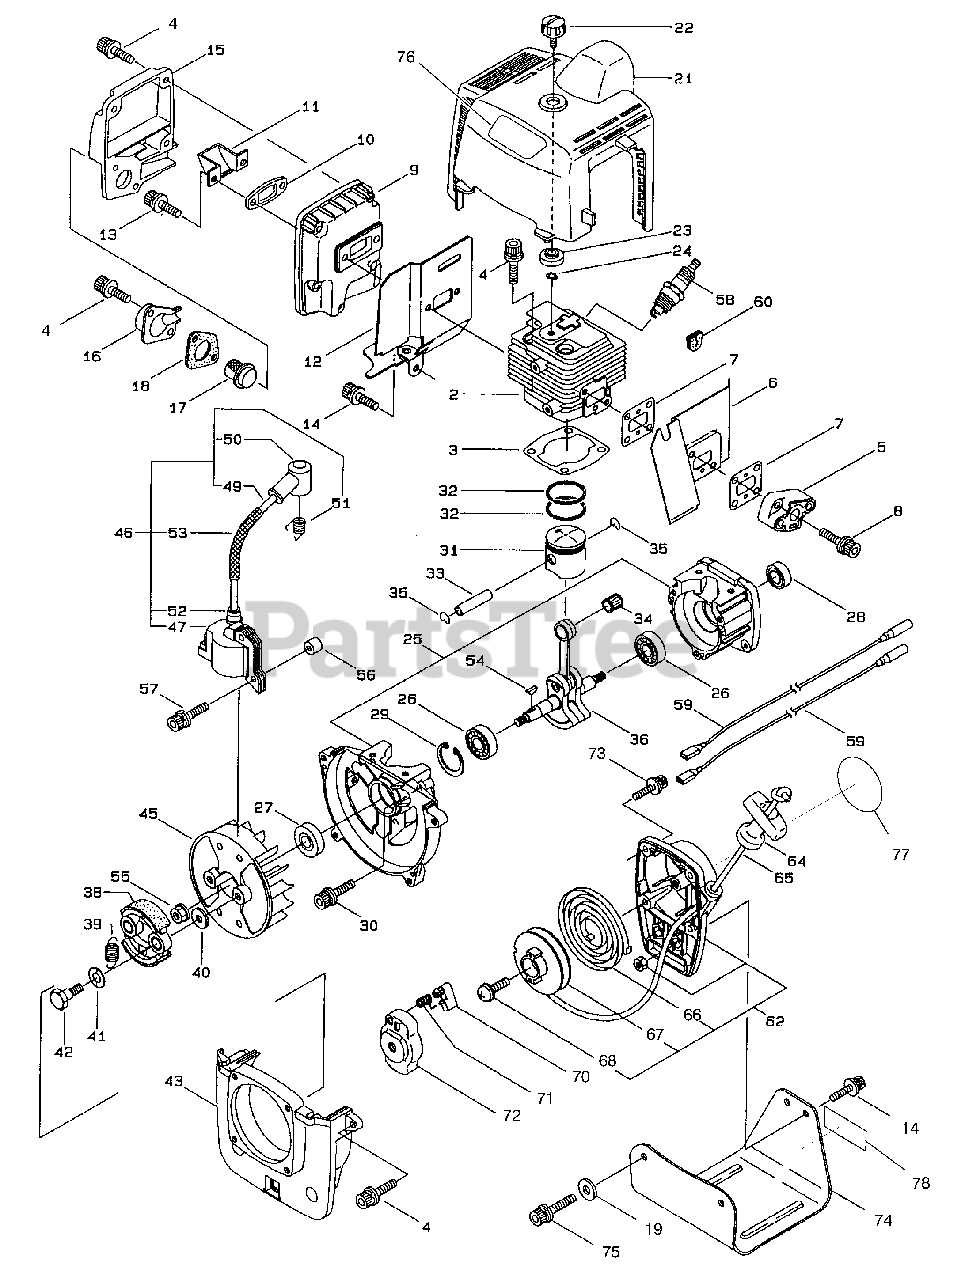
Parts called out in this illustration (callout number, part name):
2	Cylinder
4	Cap Screw
5	Insulator
6	Air Duct
8	Cap Screw
9	Muffler Body
10	Deflector Plate
11	Deflector
13	Cap Screw
14	Cap Screw
15	Muffler Cover
16	Muffler Trail
17	Spark Arrestor
21	Top Cover
24	Snap Ring
25	Crankcase
27	Oil Seal
28	Oil Seal
29	Snap Ring
30	Cap Screw
31	Piston
32	Piston Ring
33	Piston Pin
34	Bearing-Needle
35	Clip-Piston
36	Crankshaft-Connector Rod Assembly
38	Clutch Shoe
39	Spring-Clutch
41	Wave Washer
43	Fan Cover
45	Rotor-Fan
46	Ignition Coil Assembly (Incl. Ref. #47-53)
49	Spark Plug Wire
50	Plug Boot
51	Connector
53	Insulator
54	Woodruff Key
55	Nut-Rotor
57	Cap Screw
58	Spark Plug (NGK BPM6Y)
59	Wire-Coil Ground
62	Recoil Assembly (Incl. Ref. #63-68)
64	Starter Grip
65	Starter Rope
66	Spiral Spring
71	Return Spring
72	Pawl Case
73	Cap Screw
75	Cap Screw
76	Decal-Toro
77	Decal-Toro (Round)
78	Decal-Serial
